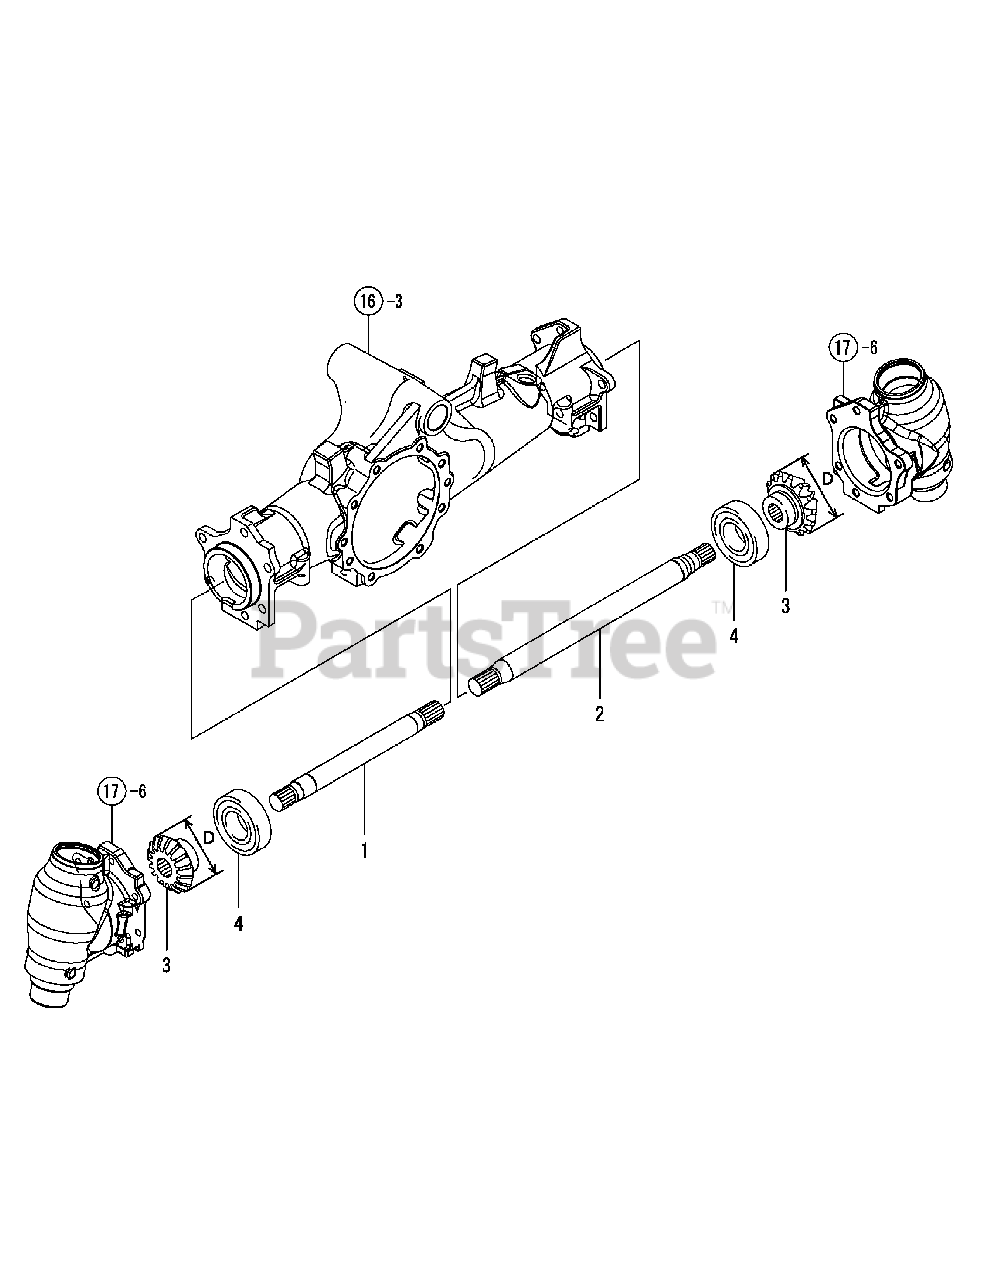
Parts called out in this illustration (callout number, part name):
1	SHAFT, DRIVE L.H.
2	SHAFT, DRIVE R.H.
3	PINION, FRONT 1ST Dia = 70MM
